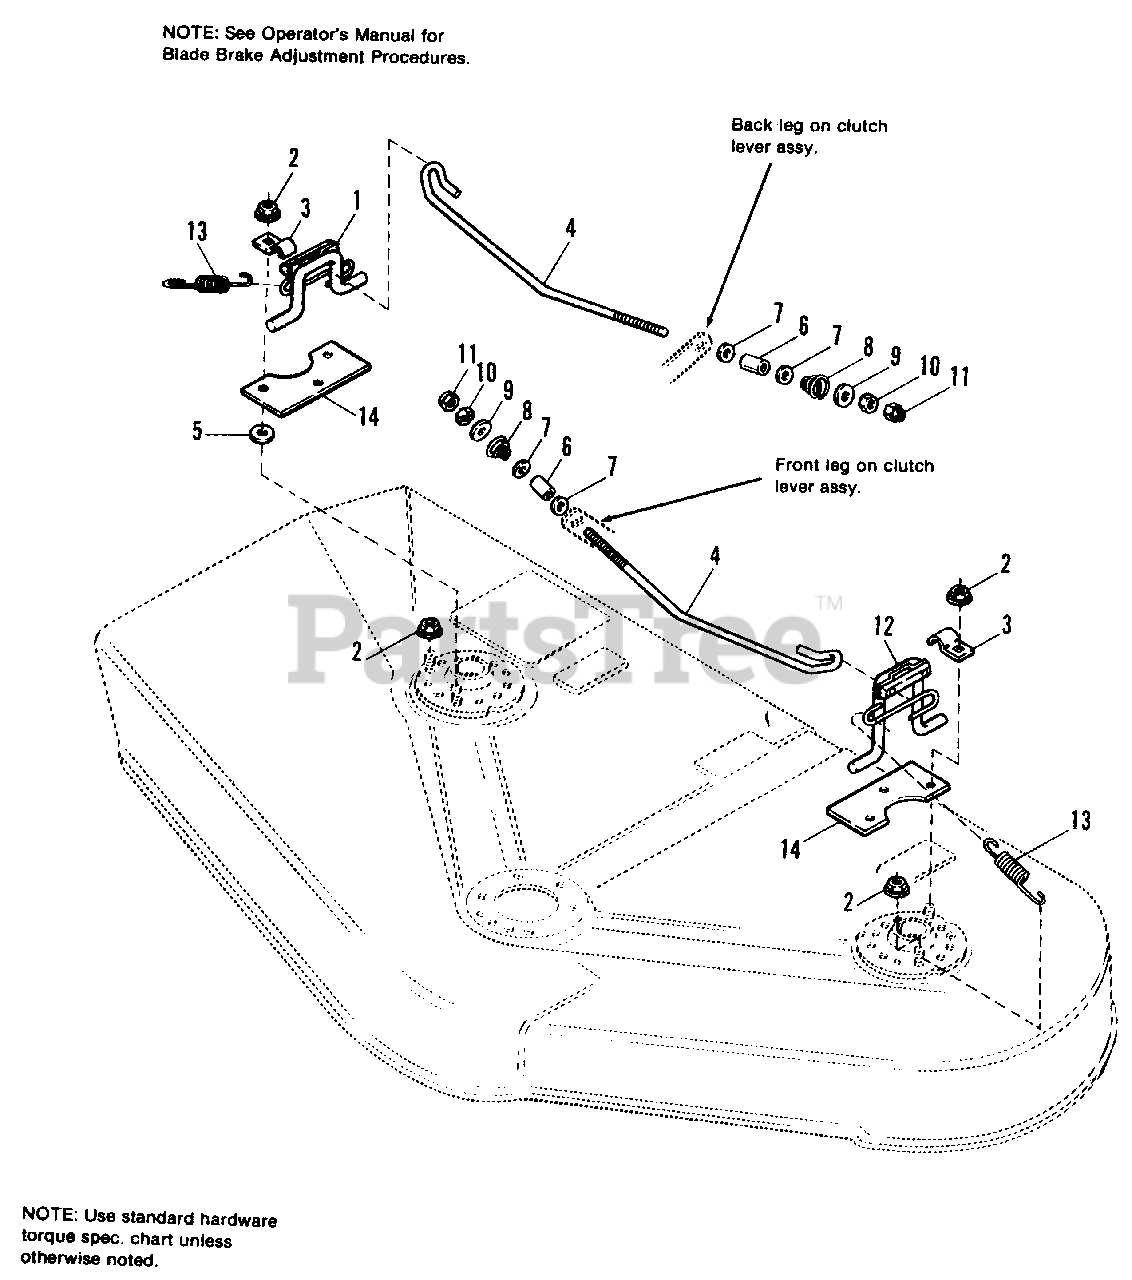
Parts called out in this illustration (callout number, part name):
1	ROD ASSY., Brake, R.H. w/Pad
2	NUT, Hex, Flange Lock, 5/16-18
4	ROD, Brake, 42"
4	ROD, Brake, 48"
5	WASHER, 13/32 x 1
7	WASHER, 1/4
9	WASHER, 11/32 x 1
10	NUT, Hex Full, 1/4-20
11	NUT, Hex Lock, Esna Light, 1/4-20
12	ROD ASSY., Brake, L.H. w/Pad
13	SPRING, Extension
